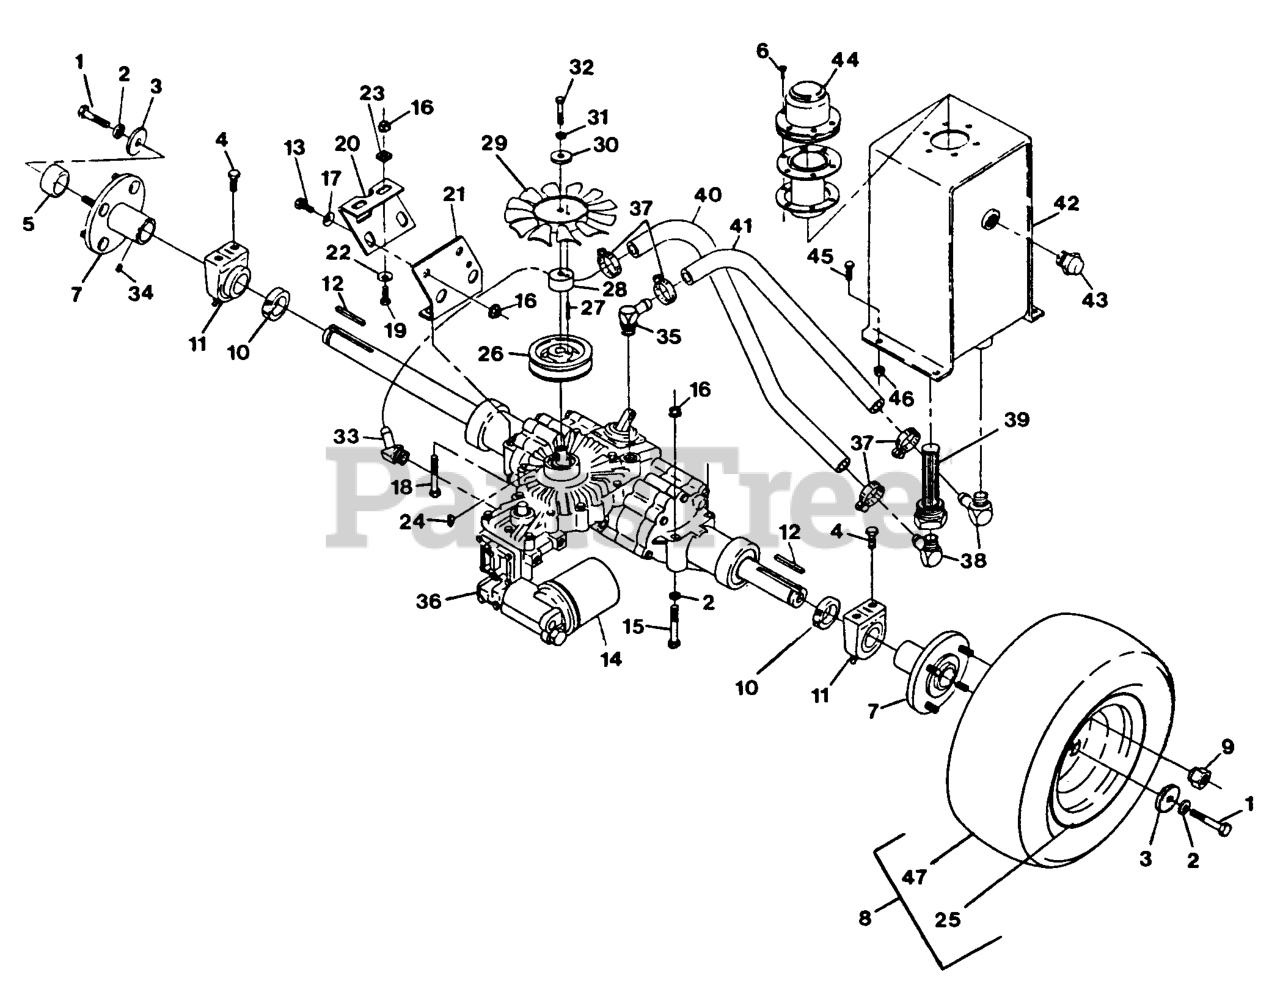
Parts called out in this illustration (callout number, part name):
8	WHEEL AND TIRE ASM
11	BEARING,PILLOW BLOCK
12	KEY,MACH HRD
28	SPACER,FAN
29	FAN,7"OD/10BLADE
30	WASHER-RETAINER, PULLEY
31	WASHER-LOCK
33	ELBOW-45DEGOR/HSEBRB
34	NUT-RETAINING
37	CLAMP-HOSE
39	STRAINER,SUCTION
40	HOSE,HYDRAULIC 16.5
41	HOSE,HYDRAULIC 8.0
43	OIL EYE,HYDRAULIC TANK
44	BREATHER,FILLR & CAP
